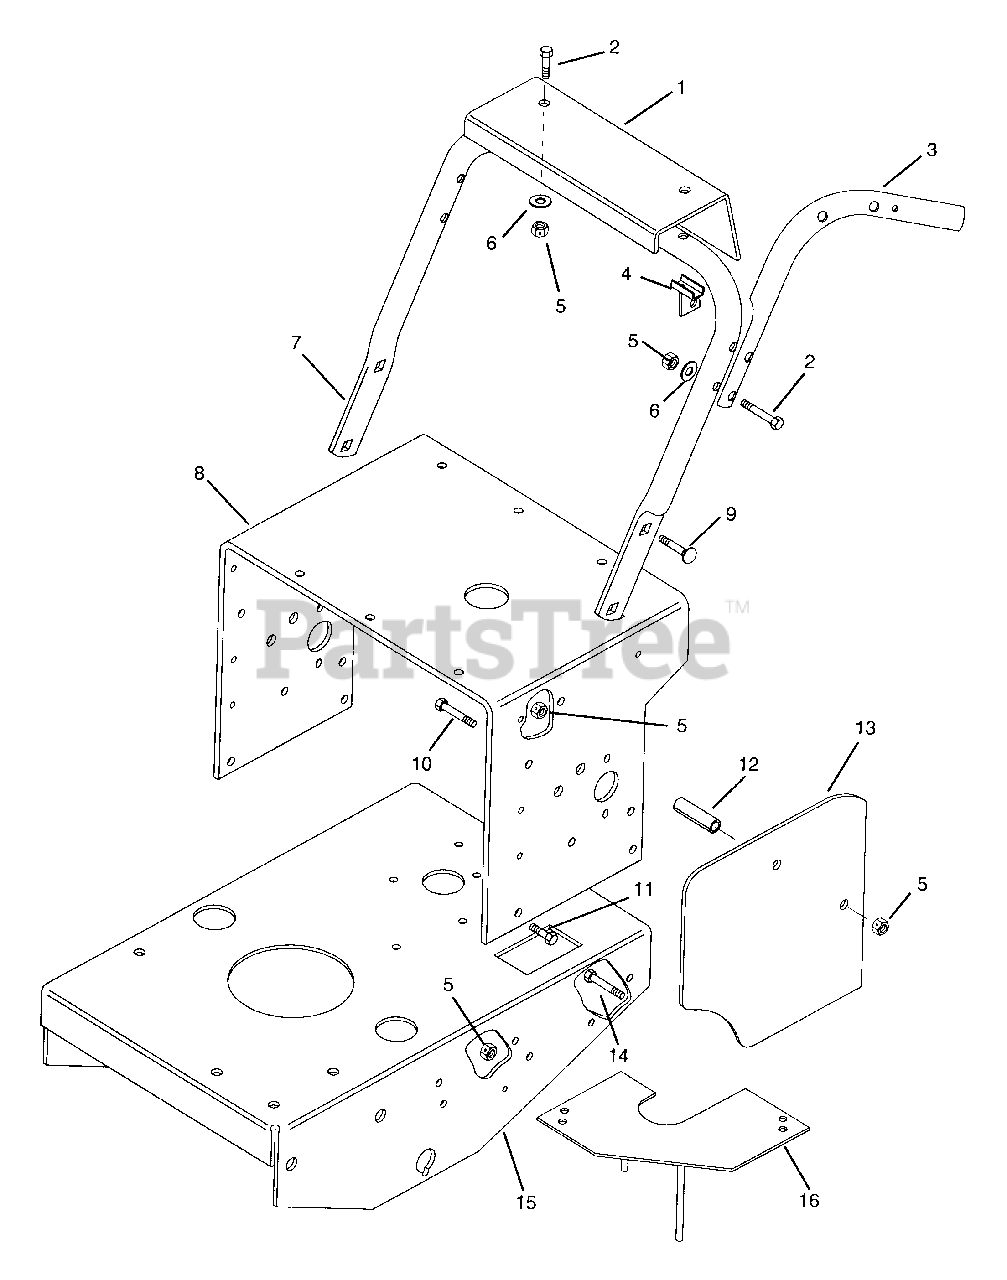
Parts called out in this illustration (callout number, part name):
1	Panel-Instrument
2	Bolt-Hex .38-16 x 2.00 Grade 5
3	Handlebar Left Hand
3	Handlebar Right Hand
4	PTO Lever Mounting Bracket
5	Nut-Locking-Center .375-16
6	Washer-Flat-Steel .406 x .812 x .065
7	Lower Handlebar-Pro 100
8	Bolt-Round Head Square Neck .38-16 x 1.0
9	Bolt-Hex .38-16 x 4.00
10	Bolt-Hex .38-16 x 1.00 Grade 5
11	Bolt-Hex .38-16x 1.00 Grade 5
12	Bushing-Spacer 3.25 x 3/8 ID x 5/8 OD
13	Guard-Drive Pro-100 Side Cover
14	Bolt-Hex.38-16 x 1.50 Grade 5
15	Pro-150 Main Frame
16	Belt Brake Finger-Deck Clutch
